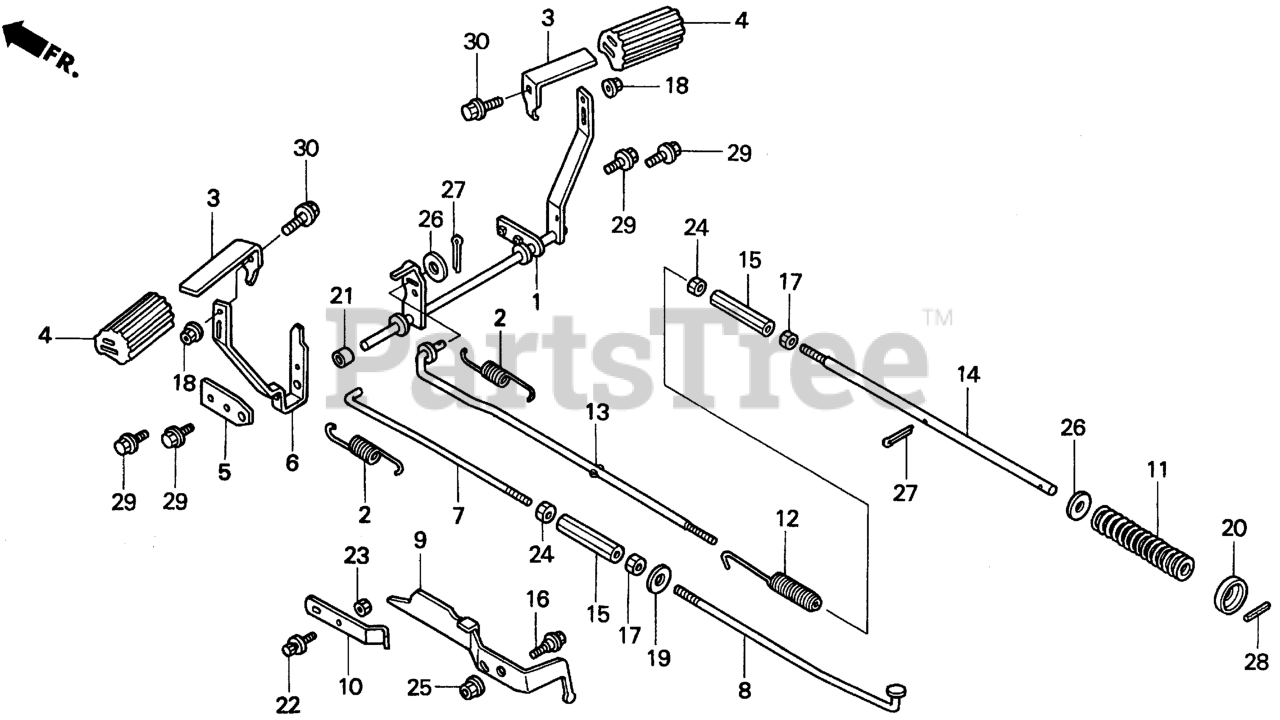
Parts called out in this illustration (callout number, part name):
1	PEDAL, BRAKE
2	SPRING, BRAKE PEDAL
3	BRACKET, BRAKE/CLUTCH
4	RUBBER, PEDAL
5	PIVOT, BRAKE PEDAL
6	PEDAL, CLUTCH
7	ROD A, CLUTCH
8	ROD B, CLUTCH
9	LEVER, PARKING BRAKE
10	SPRING, PARKING BRAKE LEVER
11	SPRING, BRAKE LOAD SETTING
12	SPRING, BRAKE DAMPER
13	ROD, RR. BRAKE
14	ROD B, RR. BRAKE
15	JOINT (8MM)
16	BOLT, ADJUSTING ARM
17	NUT, HEX. (8MM)
18	NUT, FLANGE (8MM)
19	WASHER A, HANDLE HOLDER SETTING
20	WASHER, PLAIN (0.63)
21	COLLAR (22.2X2.3X16)
22	BOLT-WASHER (5X12)
23	NUT, HEX. (5MM)
24	NUT, HEX. (8MM)
25	NUT, FLANGE (8MM)
26	WASHER, PLAIN (10MM)
27	PIN, SPLIT (4.0X22)
28	PIN, SPRING (4X25)
29	BOLT, FLANGE (8X18)
30	BOLT, FLANGE (8X28)
